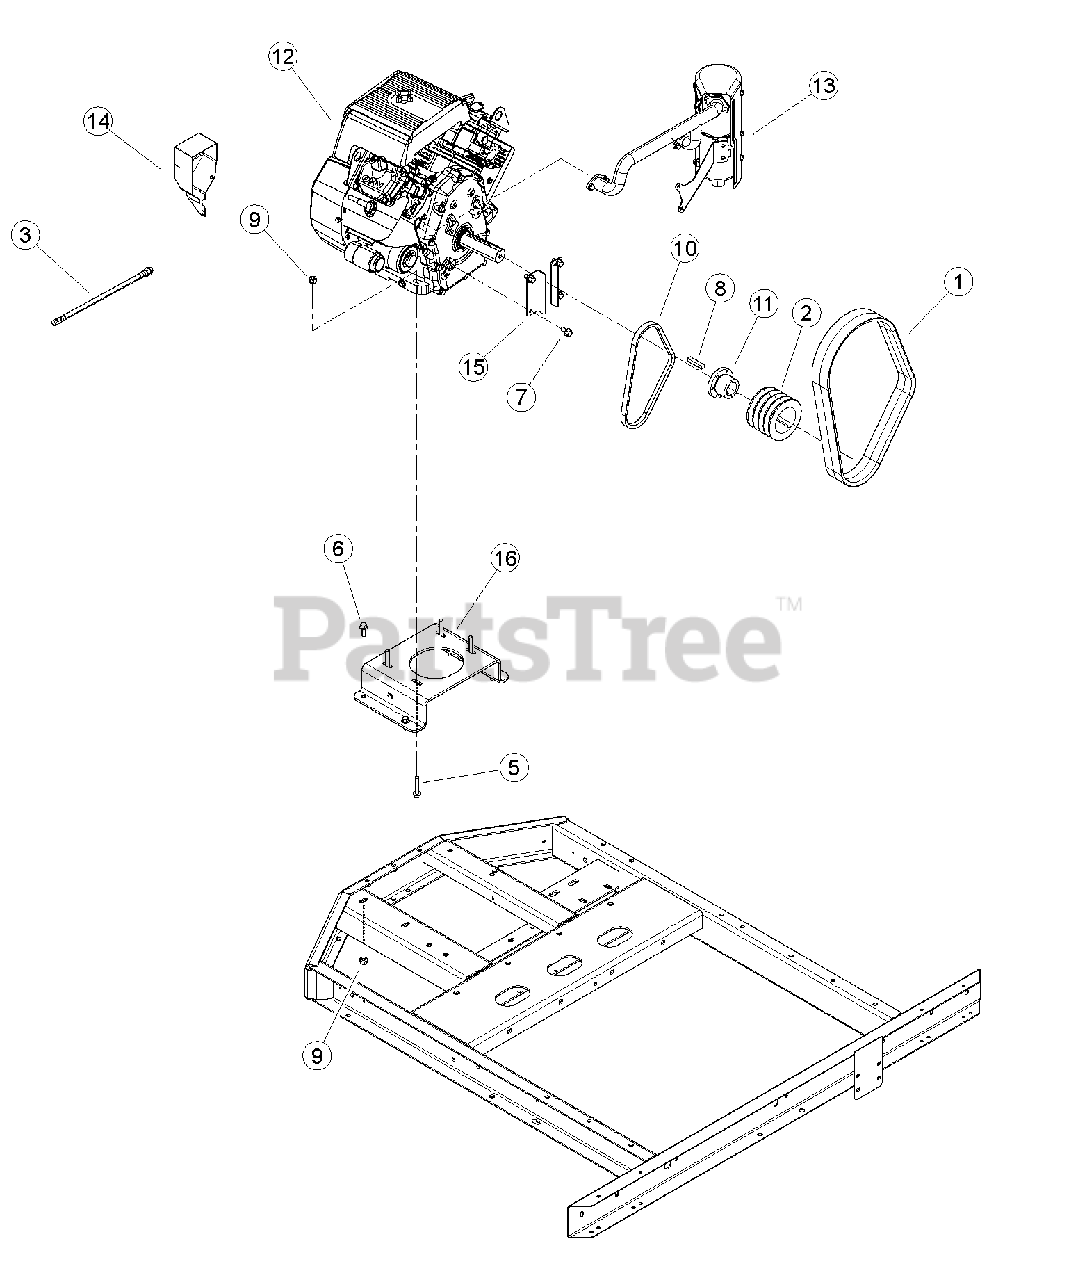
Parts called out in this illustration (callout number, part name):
1	BELT, 3RB48 ARAMID
2	SHEAVE, 4B4.2 SD
3	HOSE ASSEMBLY, CRANKCASE DRAIN
4	BOLT, 3/8 X 1" GR5 CRG NC ZP
5	BOLT, 3/8 X 2 FLANGE NC
6	BOLT, 3/8 X 1 FLANGE NC
7	BOLT, 3/8 X 3/4 FLANGE NC
8	KEY, 3/8" SQ X 2" LG PLAIN
9	NUT, 3/8-16 NYLOCK FLANGE
10	BELT, 29" C/S
11	BUSHING, SD 1-7/16"
13	MUFFLER, SUBARU V-TWIN OIL SIDE
14	CONTROL, SUBARU V-TWIN IGNITION/HOUR
15	SHIELD, SUBARU CRANKSHAFT
16	BASE, SUBARU ENGINE
